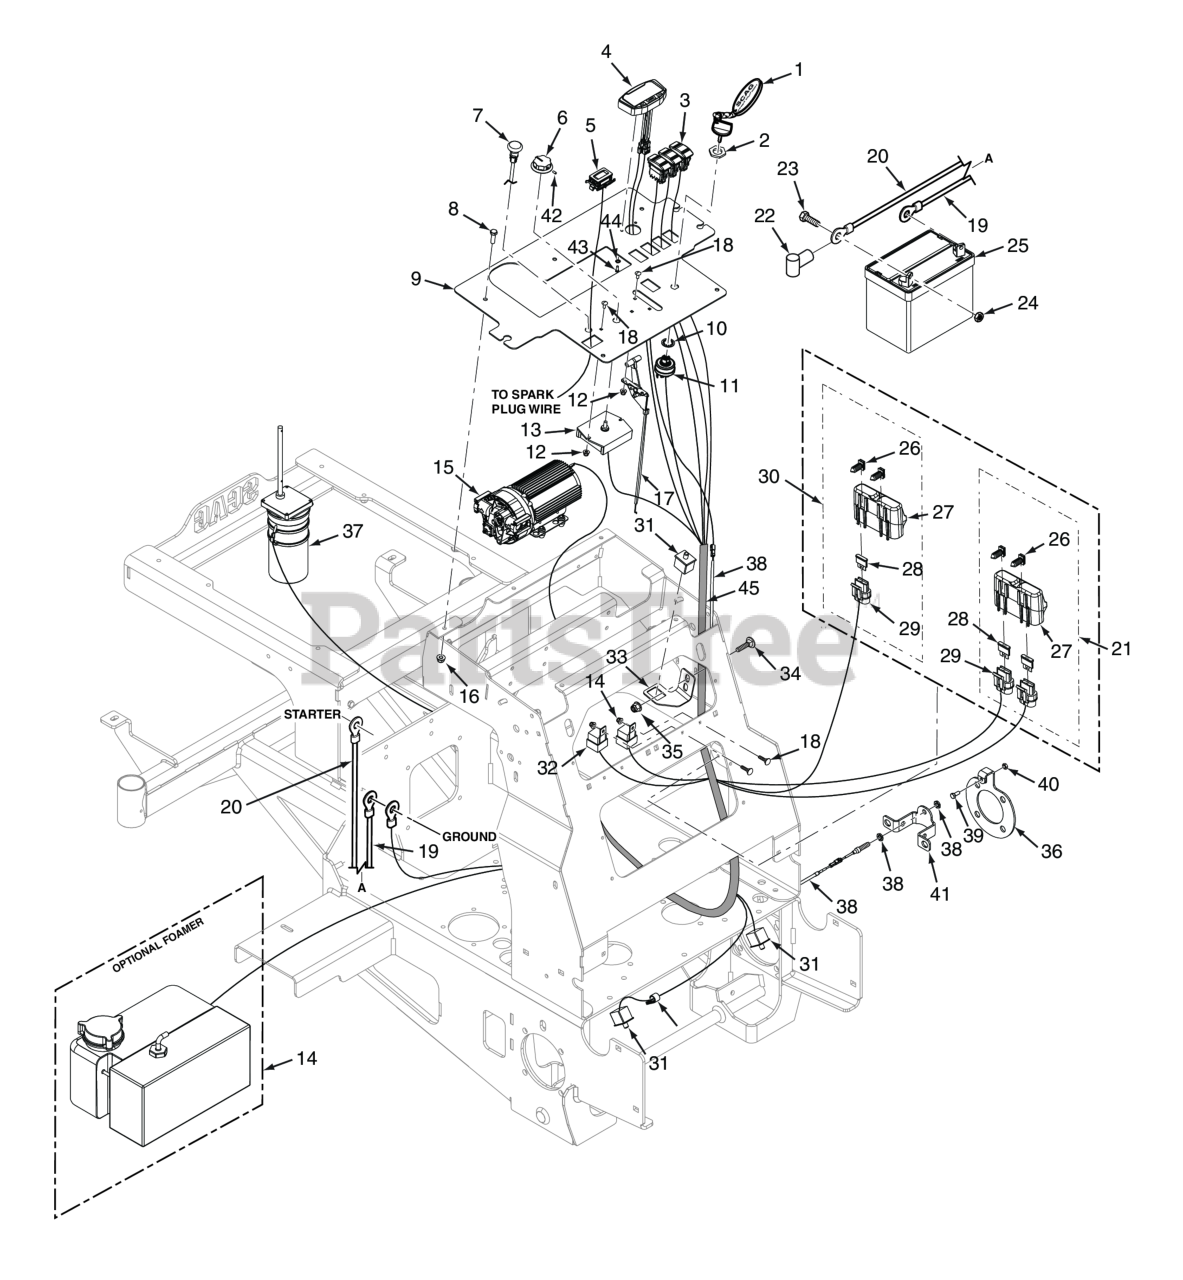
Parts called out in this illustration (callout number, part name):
1	Key, Assembly w/Fob
2	Nut, 5/8-32 Special
3	Switch, Rocker
4	Display, Trail Tech
5	Hour Meter, Inductive
6	Knob (Incl #38)
7	Choke Control (excludes EFI models)
8	Bolt, Hex 5/16" - .375 x 1.00- Stainless Steel
9	Instrument Panel w/ Decal
10	LOCK WASHER, 5/8" INTERNAL TOOTH
11	KEY SWITCH(INCLUDES MOUNTING HARDWARE)
12	Locknut, #10 - 32 Elastic Stop - Stainless Steel
13	Motor Controller
14	Foamer Accessory (optional)
15	Pump, 12V Electric
16	Locknut, 5/16-18 Flg. Elastic Stop - Stainless Steel
17	Throttle Control, SVR
18	Bolt, Carriage #10 - 32 x .50 - Stainless Steel
19	Battery Cable, 31-1/2" Black (25KA, 26DFI, 31DFI) - Kawasaki
20	Battery Cable, Red
21	Double Fuse Assy.
22	RUBBER BOOT
23	BOLT, HEX HEAD, 1/4-20 X 3/4 GR.5
24	Nut, 1/4 - 20 Hex
25	Battery, 350 CCA (not available through Scag)
26	Clip, Fuse Holder
27	Cover, Sealed Double
28	FUSE, 20 AMP BLADE TYPE AUTOMOTIVE
29	Fuse Holder Assembly
30	Double Fuse Assy.
31	Switch, Double Pole - Plunger
32	Relay, 12V 40 AMP Standard
33	Mounting Bracket, Brake Switch
34	Bolt, Carriage 5/16 - 18 x 1" - - Stainless Steel
35	Locknut, 5/16-18 Flg. Elastic Stop - Stainless Steel
36	Plate, Hub Magnet Holder
37	Gear Motor, Electric
38	Wire Harness, Display
39	Bolt, Magnetic
40	Nut, M6 x 1.00
41	Plate, Speed Sensor
42	Set Screw, #8 - 32 x .375
43	Bolt, Hex Head M4-.7 x 10
44	Lockwasher, M4-1.1 x 7.6 x .8
45	Wire Harness, STS
